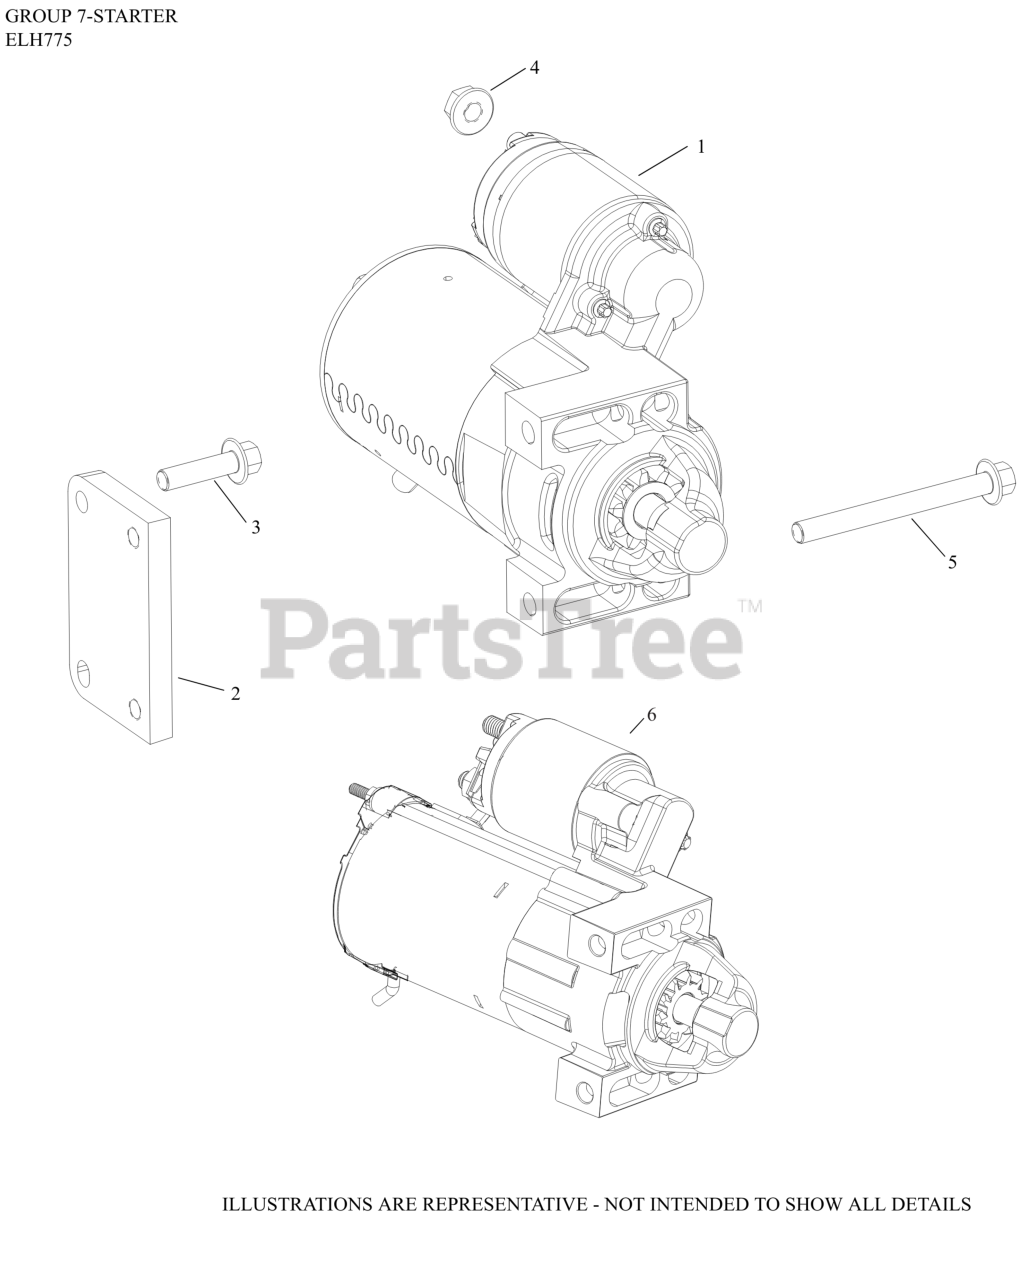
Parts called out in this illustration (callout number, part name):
1	STARTER, SOLENOID SHIFT-(#2509824S)
2	PLATE, STARTER
3	SCREW, FLG M8X1.25X30
4	NUT, FLG M8X1.25
5	SCREW, FLG M8X1.25X80
